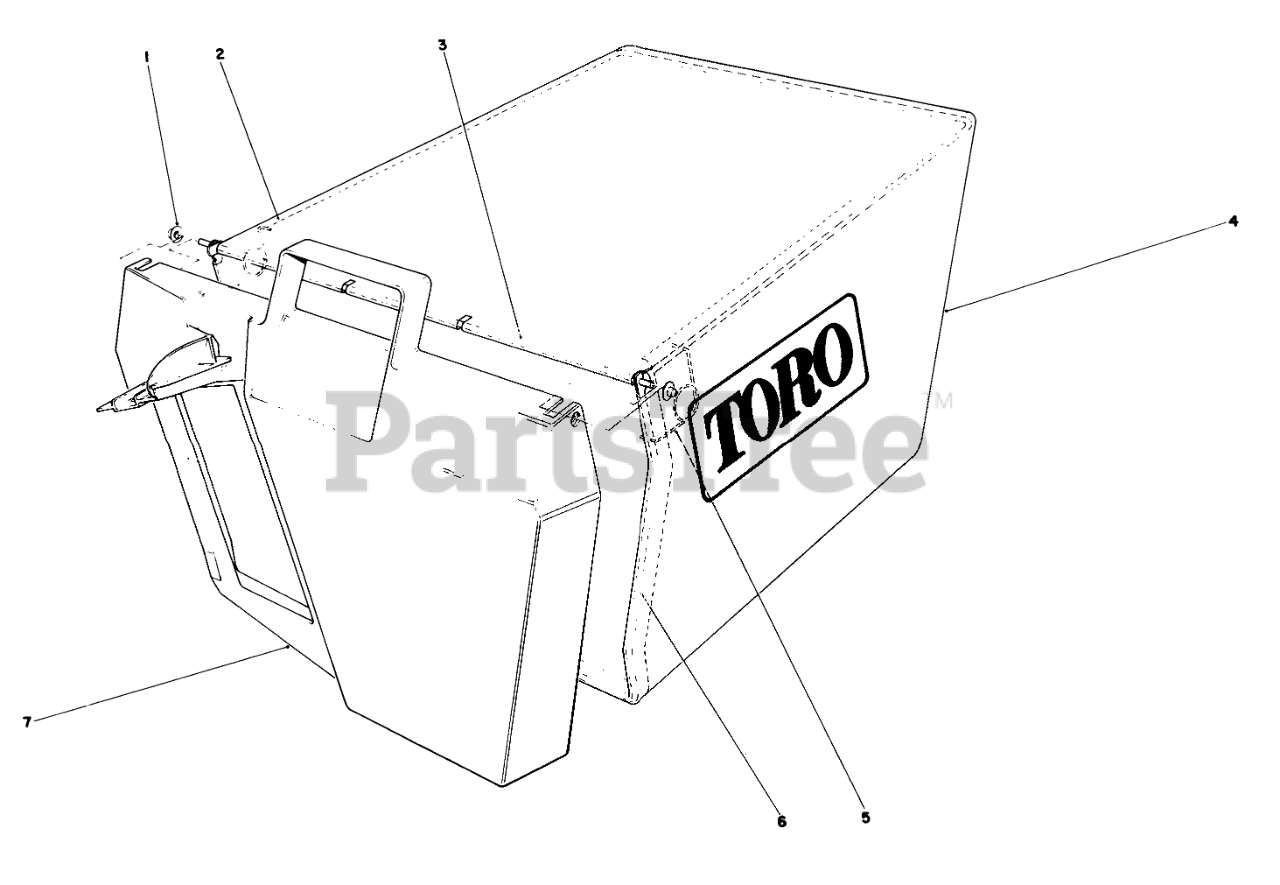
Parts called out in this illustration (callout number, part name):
1	NUT-PUSH
2	FRAME-BAG, UPPER
3	HINGE-DOOR, BAG
4	Bag
5	SPRING
6	BAG FRAME
7	Door Grass Bag
